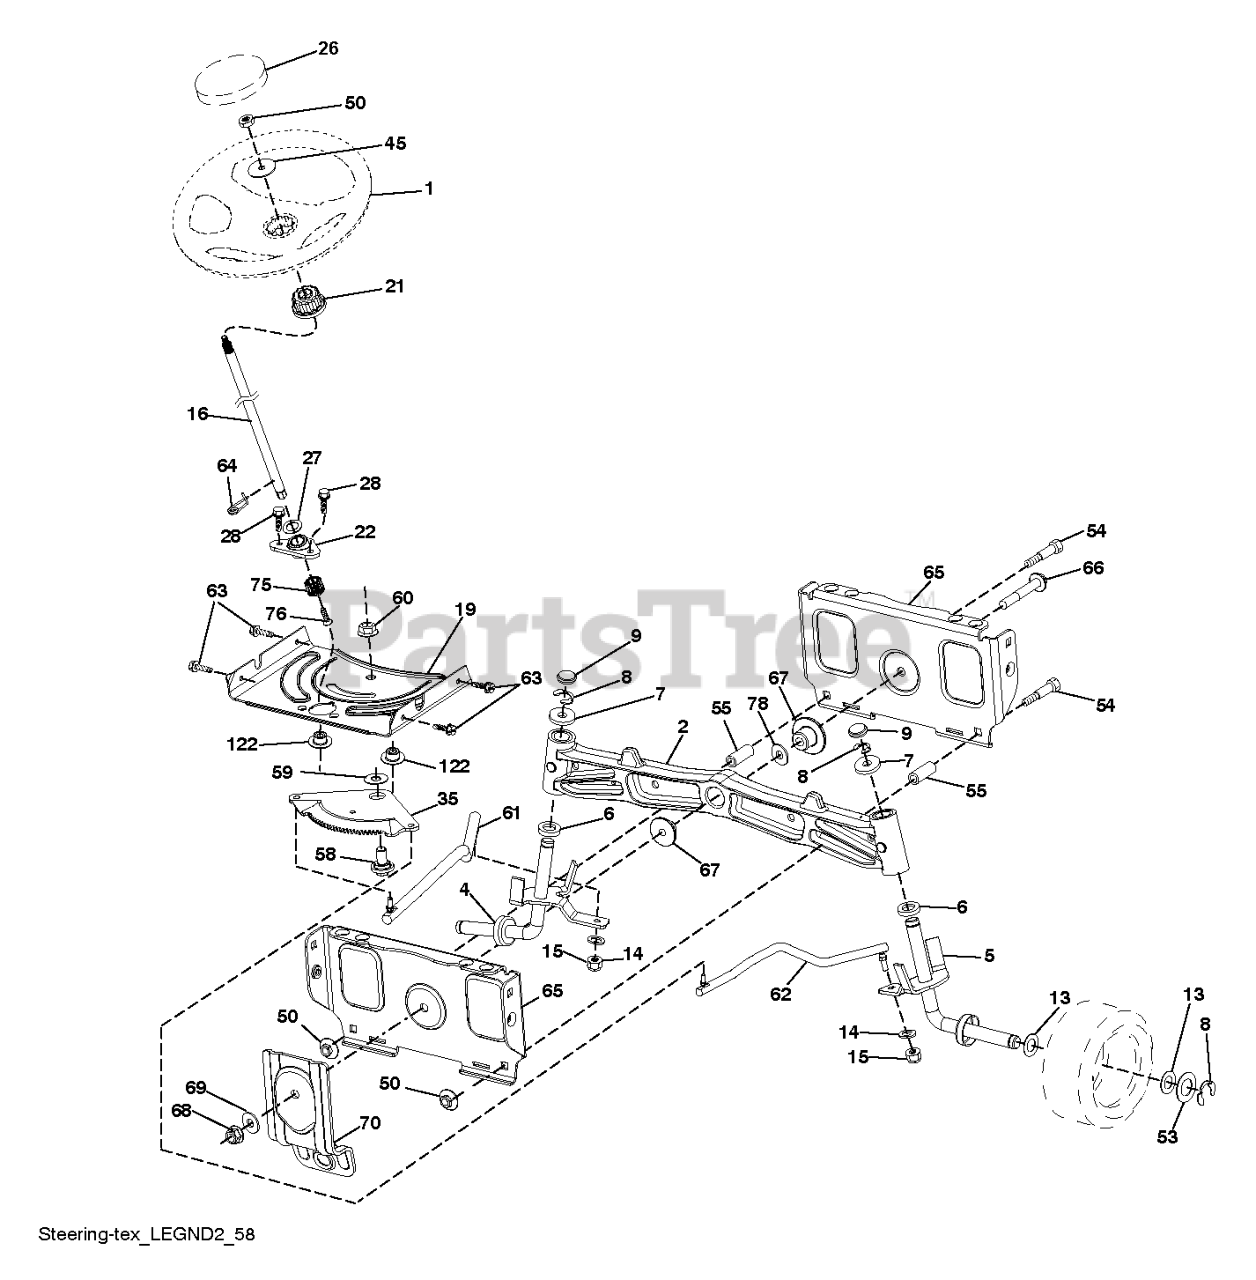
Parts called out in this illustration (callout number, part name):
1	WHEEL.STEER.HUSQ.SR.498.OVMLD
2	AXLE.CAST.IRON
4	SPINDLE.WELDED.LH.16"TEX
5	SPINDLE.WELDED.RH.16"TEX
6	THRUST WASHER
9	CAP.SPINDLE.BLACK
14	WASHER, LOCK 3/8
15	NUT CROWNLOCK 3/8-24
16	SHAFT.STEER.2HIGH.SPLND.PLATED
19	PLATE.STEER.DDL.NLT/NG
21	ADAPTER.WHEEL.STEER.SPLND.ALUM
22	BEARING.SHAFT.STEER.LOWER.625
26	INSERT.CAP.WHL.STRG.HUSQ.PREM
27	WASHER LT
28	SCREW, 3/8-16X3/4
35	GEAR.SECTOR.PLATE.DDL.
45	WASHER.3/8ID.2-3/8OD.12GA.PLTD
50	NUT LOCK FLG 3/8-16 UNC
53	WASHER.HARDENED
55	SPACER.BRACE.AXLE
58	BOLT.SHOULDER.SECTOR.P
59	WASHER.THURST.SECTOR.S
60	NUT FLANGE LOCK 5/8-11
61	DRAGLINK.LH.BALLSTUD.D
62	DRAGLINK.RH.BALLSTUD.D
63	SCREW
64	RETAINER.CLIP.SPRING.S
65	BRACE.AXLE.FRONT.NLT/N
66	BOLT HEX FGHD 7/16-14 X 3 SERR
67	BUSHING.PM.FRONT AXLE
68	NUT.LOCK.FLANGE.7/16
69	WASHER.1.5X.505X.118
70	BRACKET.FRT.DECK.SUSP.RR.MT431
75	PINION.ZINC PLATED
76	SCREW HEAD SOCKET LRVB
78	THRUST WASHER
122	CAP.GEAR.SECTOR.TEX
